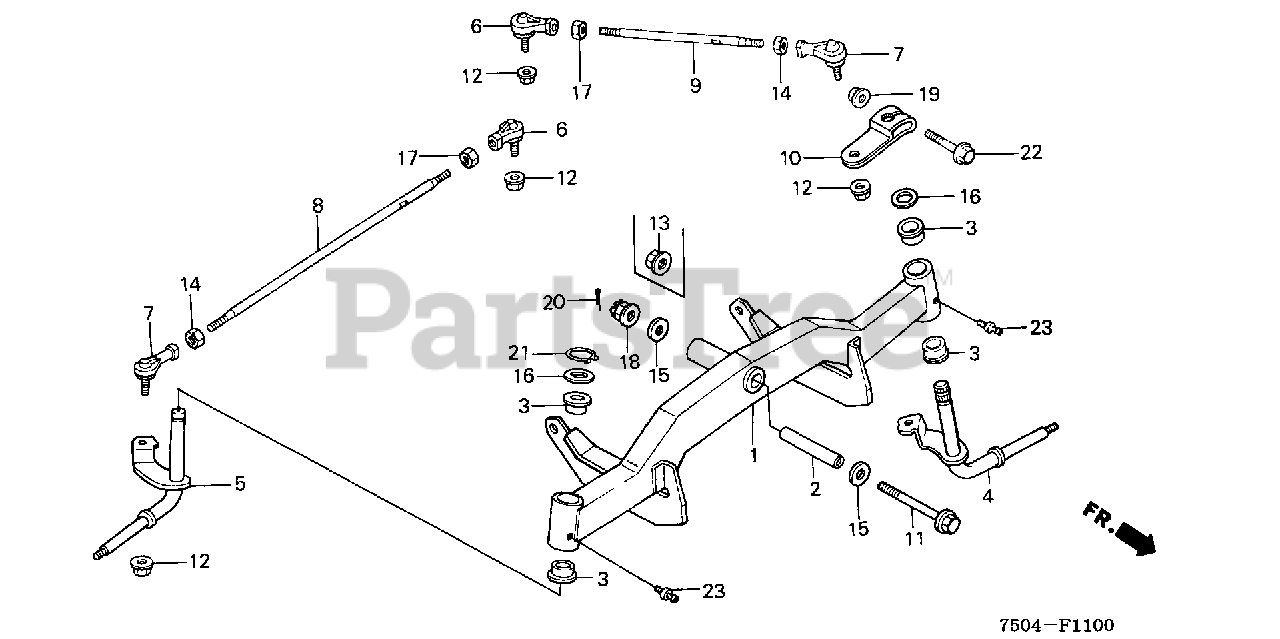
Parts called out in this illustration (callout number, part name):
2	COLLAR, FR. AXLE (NOT AVAILABLE)
3	BUSH (20X25X15.5)
4	KNUCKLE, L.
5	KNUCKLE, R. (NOT AVAILABLE)
6	JOINT, R. BALL
7	JOINT, L. BALL
10	ARM, KNUCKLE
11	BOLT, FLANGE (12X120)
12	NUT, AXLE (10MM)
14	NUT, HEX. (10MM) (LEFT HAND THREAD)
15	WASHER, PLAIN (12MM)
16	WASHER, THRUST (20MM)
17	NUT, HEX. (10MM)
18	NUT, CASTLE (12MM)
19	NUT, SELF-LOCK (8MM)
20	PIN, COTTER (3.0X45)
21	CIRCLIP (OUTER) (20MM)
22	BOLT, FLANGE (8X50)
23	FITTING, GREASE (A.76)
